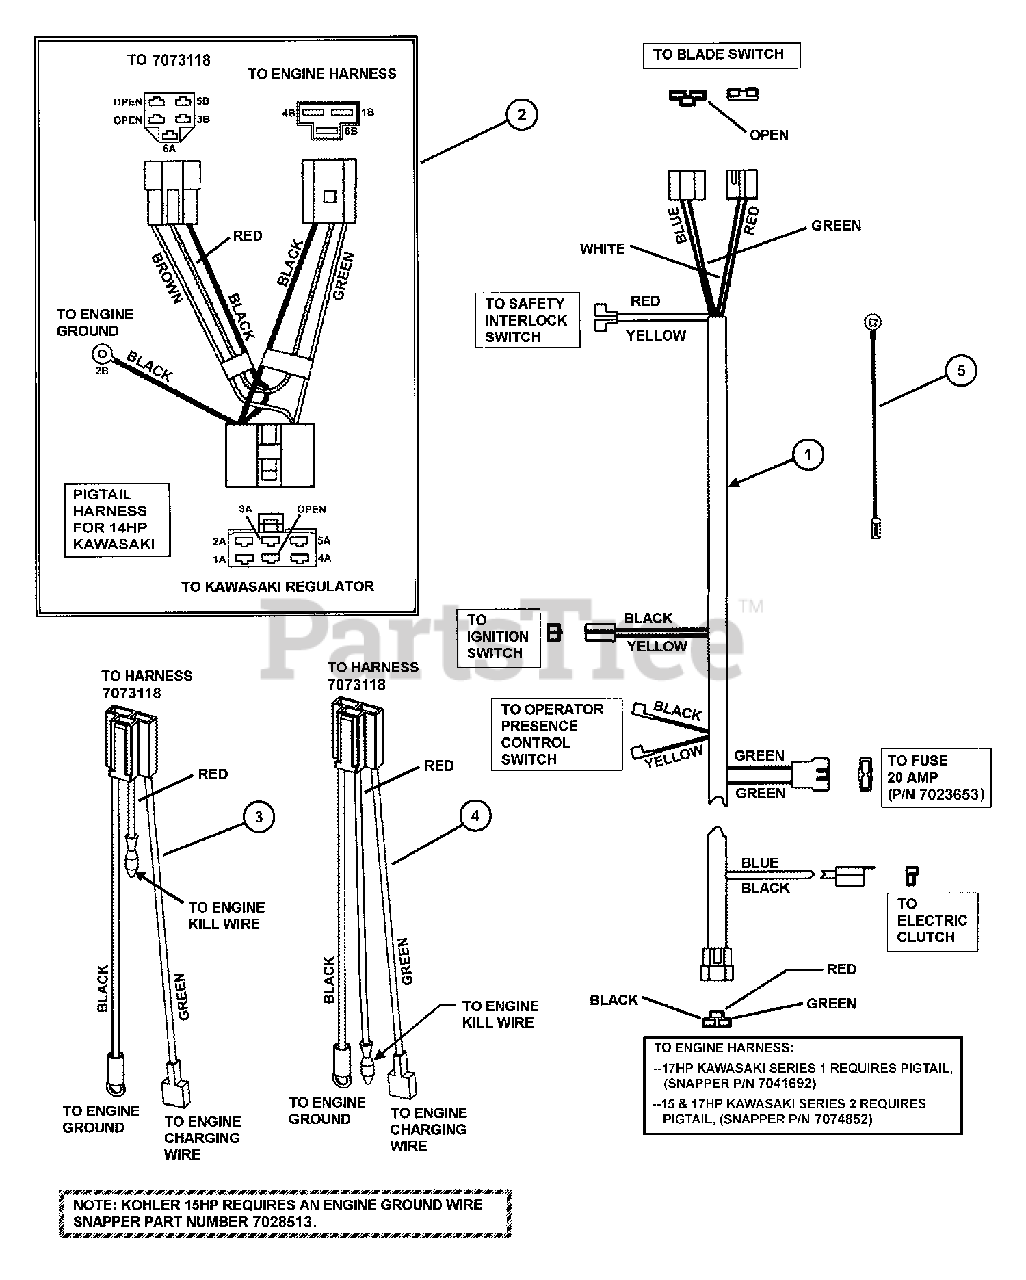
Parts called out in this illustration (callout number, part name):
1	WIRING HARNESS
2	HARNESS, Wiring Pigtail
3	HARNESS, Wiring Pigtail
4	HARNESS, Wiring Pigtail
5	WIRE, Kohler Engine Ground
